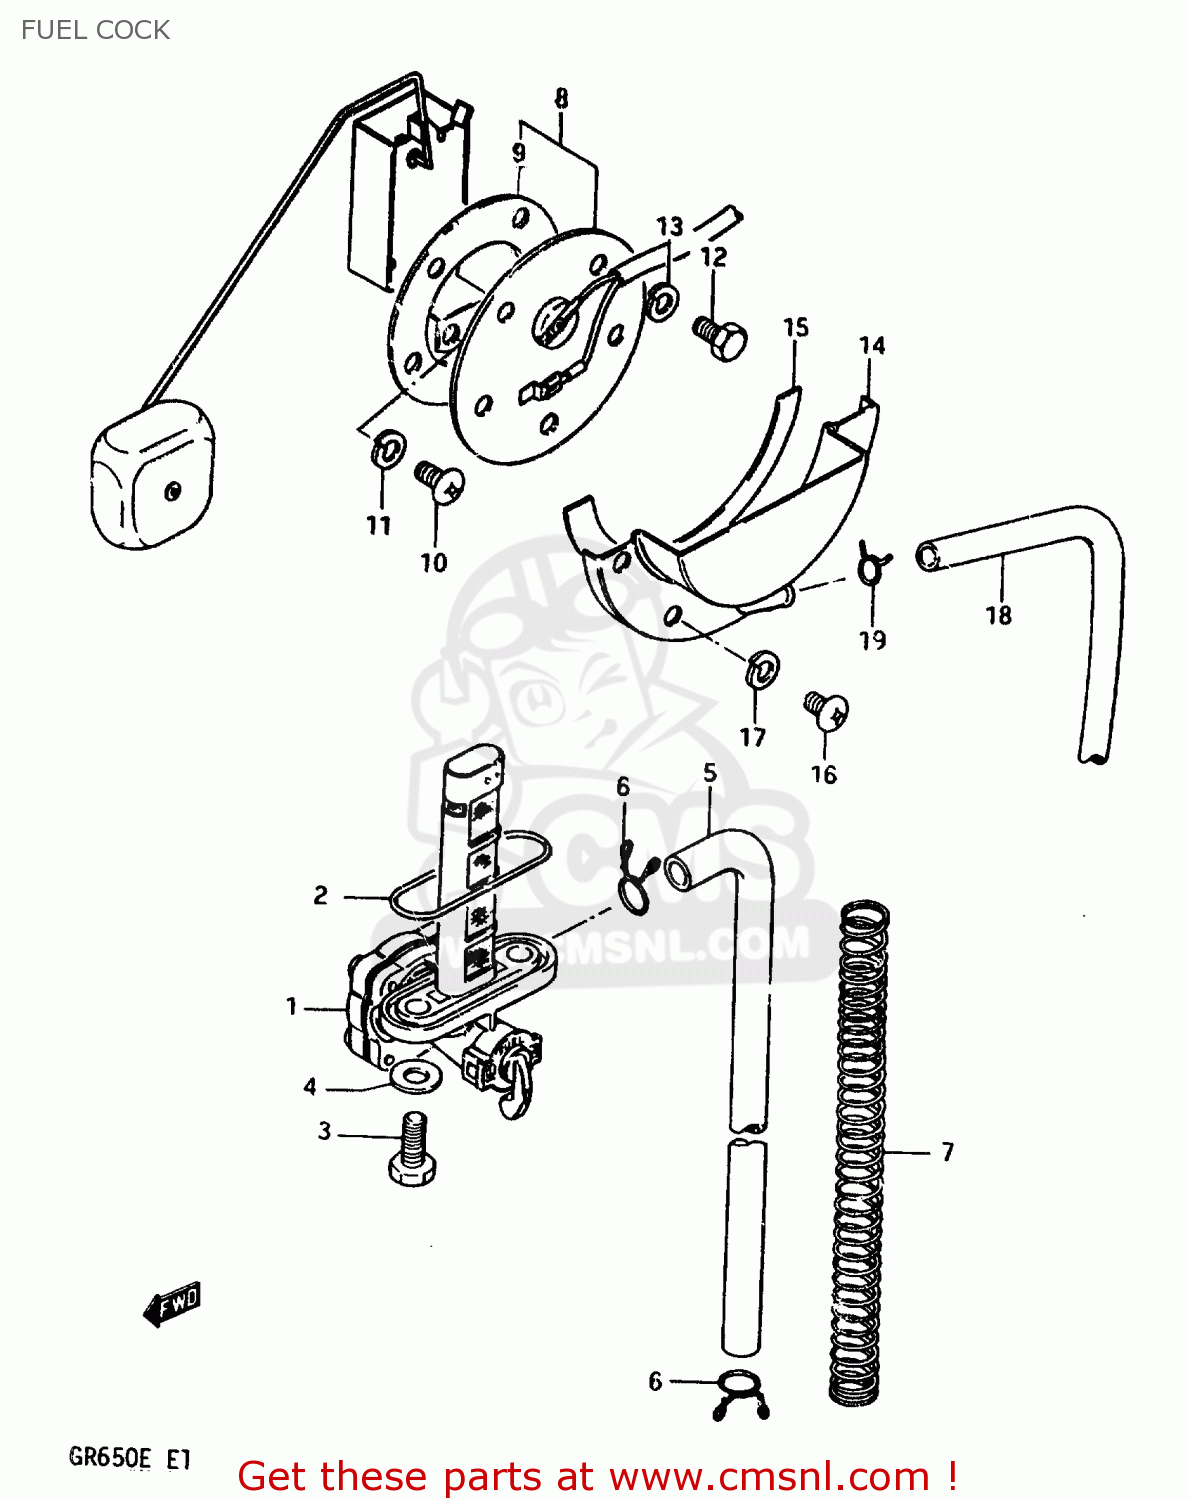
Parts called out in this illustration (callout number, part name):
1	COCK ASSEMBLY,FUEL
2	O RING
3	BOLT(6X20)
4	GASKET
5	HOSE
6	CLIP
7	SPRING
8	GAUGE ASSEMBLY,FUEL LEVEL
9	GASKET,FUEL LEVEL GAUGE (NAS)
10	SCREW
11	LOCK WASHER
12	BOLT 5X10
13	LOCK WASHER
14	PLATE,FUEL DRAIN
15	GASKET (NAS)
16	SCREW
17	LOCK WASHER
18	HOSE,FUEL
19	CLIP
